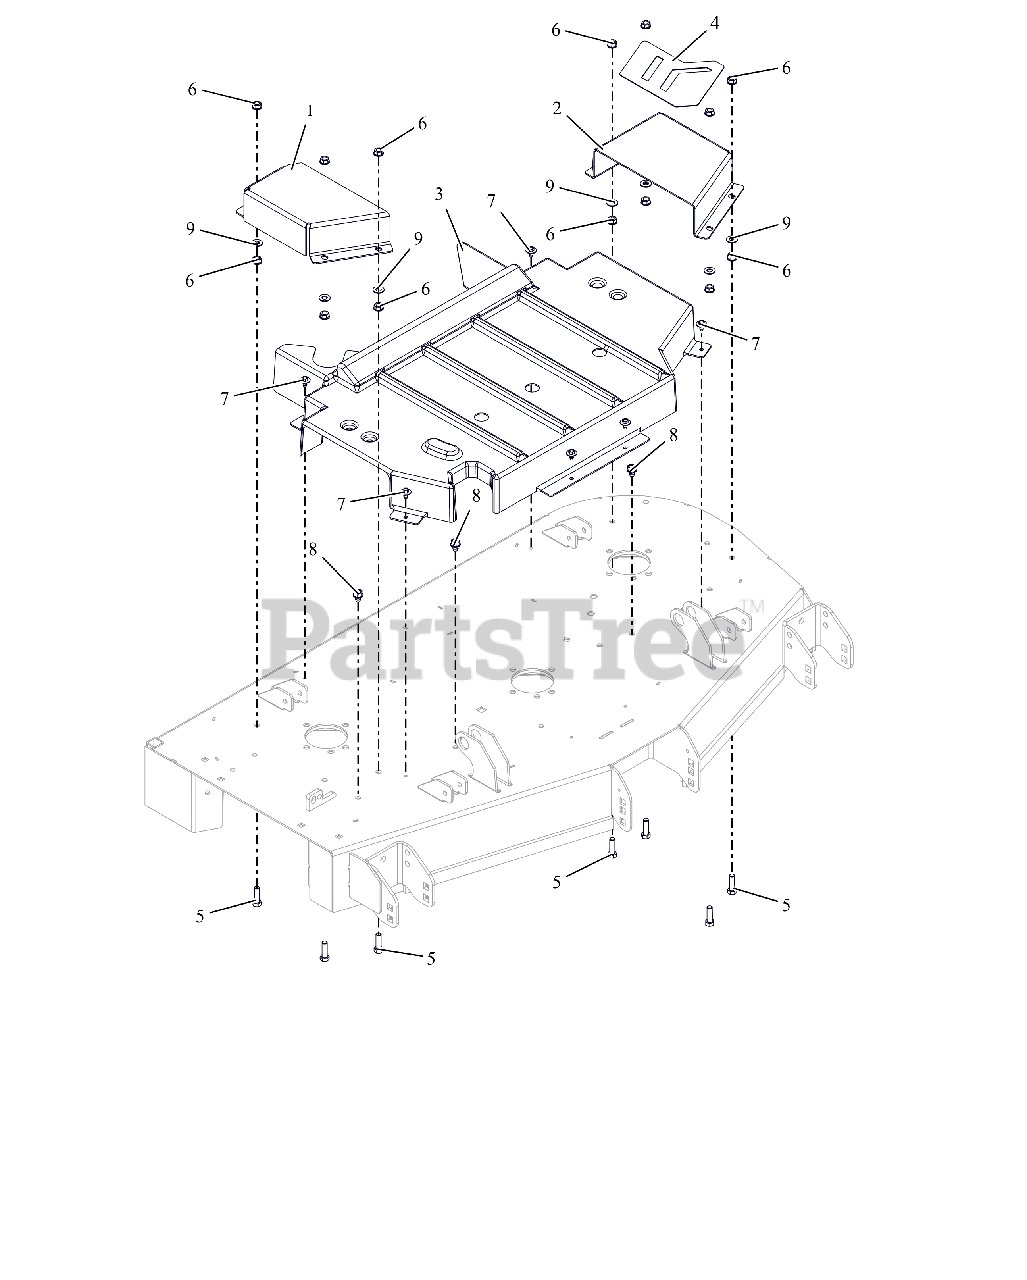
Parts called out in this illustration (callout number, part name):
1	GUARD BELT, 48" RIGHT CE
2	GUARD BELT 48" LEFT CE
3	GUARD, CENTER DECK SPINDLE CE
4	GRIP TAPE 48 BELT COVER
5	BLT, HEX .38-16X1.25 G5 ZCC
6	NUT, SPNLK-FLG .38-16 G5 ZCC
7	SCR, TAP .25-20X.50 LG HWH ZCC
8	SCR,TAP .375-16X.50 HWH TR ZCC
9	WSHR,FLT .406X.812X.065 ZCC
